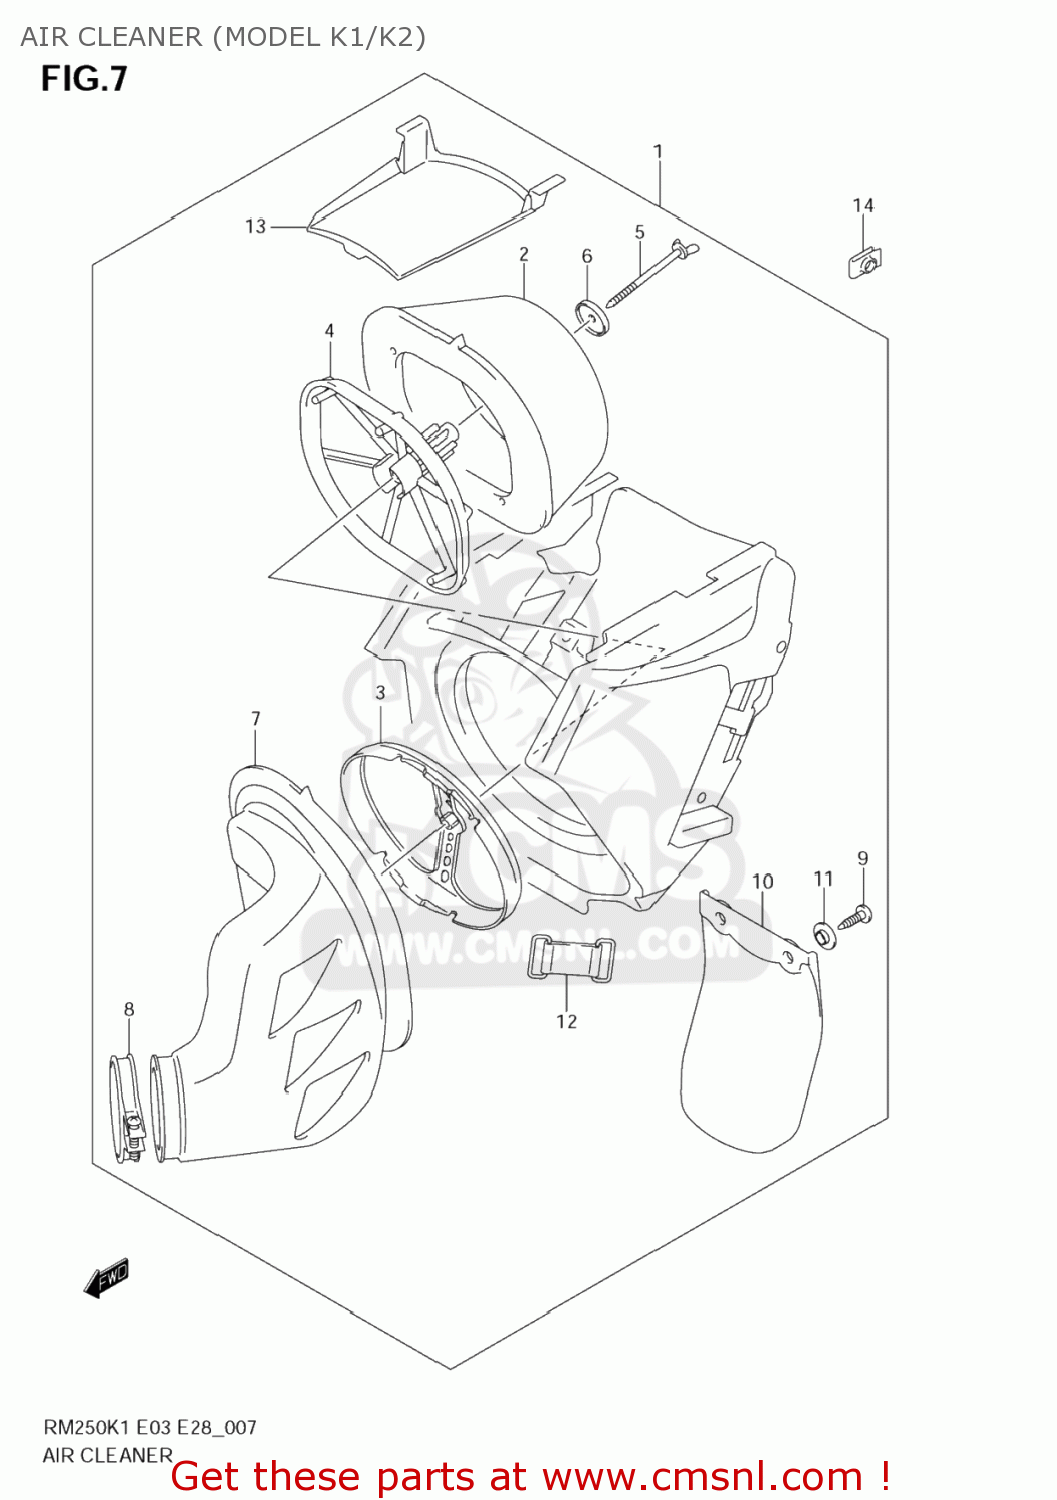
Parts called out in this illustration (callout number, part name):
1	CLEANER ASSY,AIR
2	FILTER ASSY
3	BASE,FILTER
4	HOLDER,FILTER
5	BOLT,WING
6	WASHER,AIR CLEANER
7	TUBE,OUTLET
8	CLAMP
9	SCREW
10	MUDGUARD
11	COLLAR
12	BAND(L:65)
13	CAP,AIR CLEANER
14	HOLDER,REAR BU
